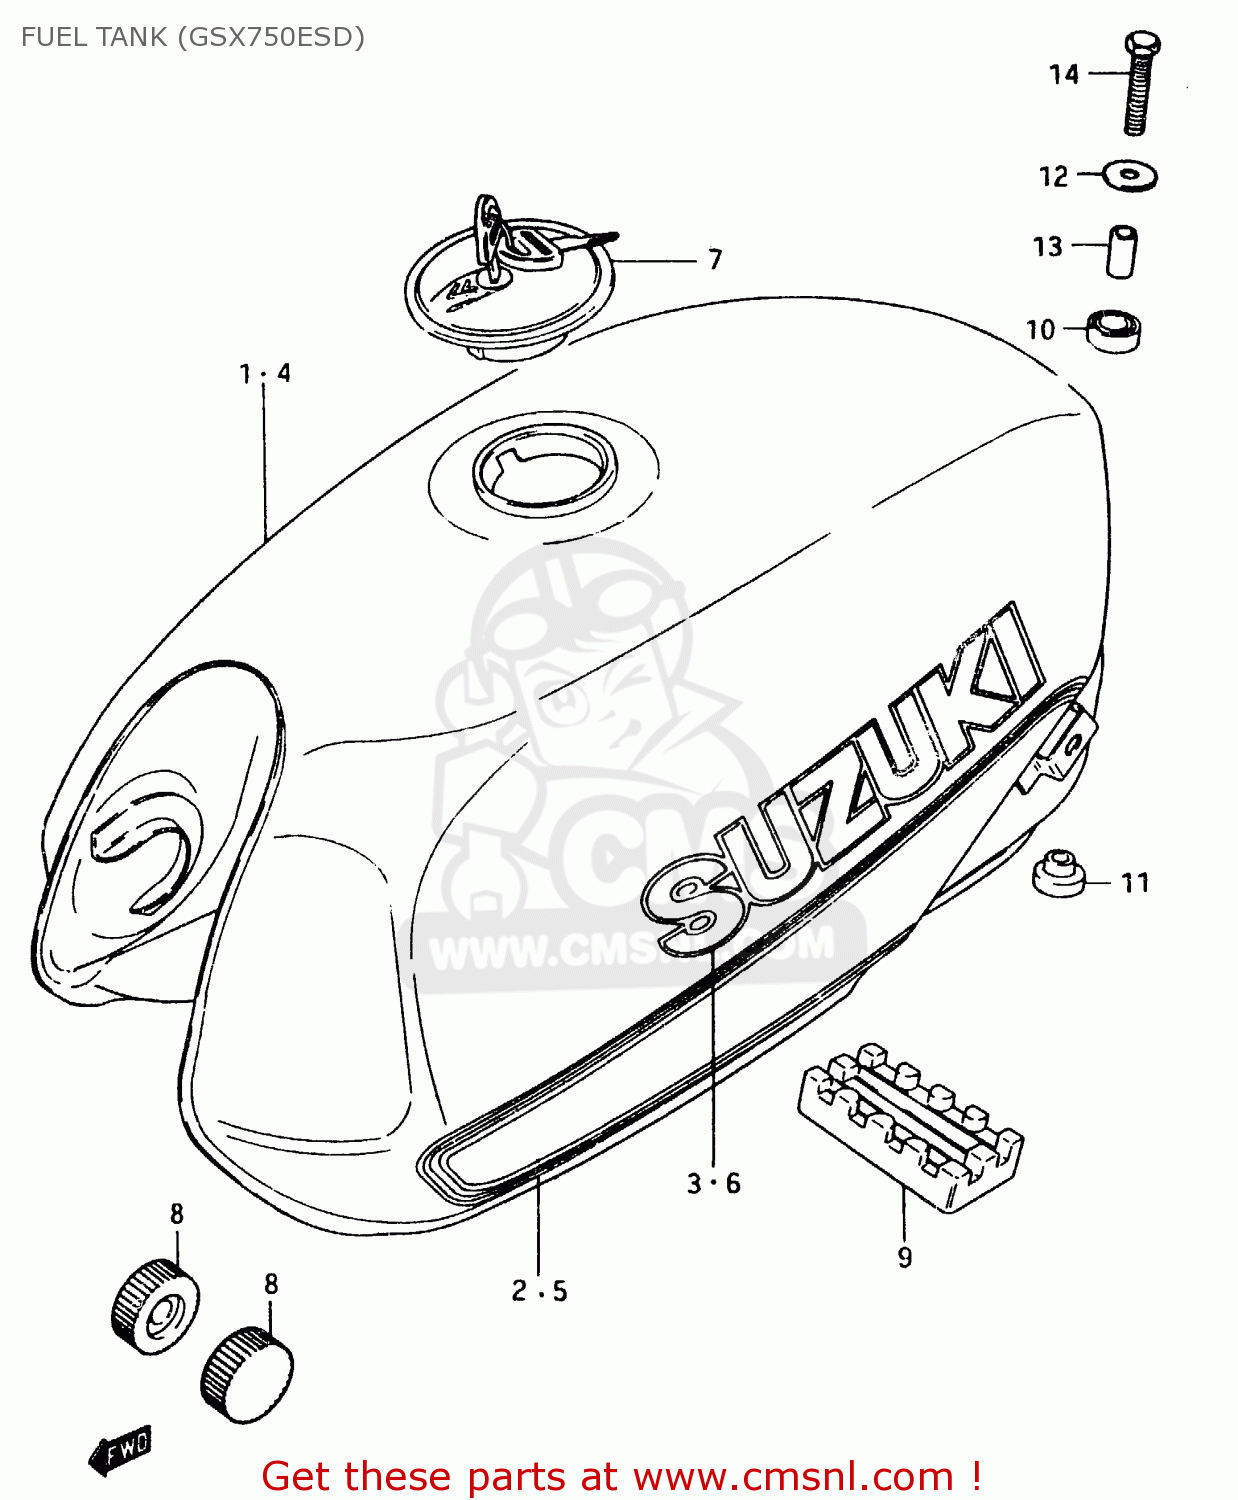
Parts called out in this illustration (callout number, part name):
1	TANK, FUEL
2	TAPE SET, FUEL TANK
3	EMBLEM,FUEL TA
4	TANK, FUEL
5	TAPE SET, FUEL TANK
6	EMBLEM
7	CAP SET,FUEL TANK
8	CUSHION
9	CUSHION,FUEL TANK CTR
10	CUSHION
11	CUSHION
12	WASHER (6.5X24X1.6)
13	SPACER
14	BOLT
